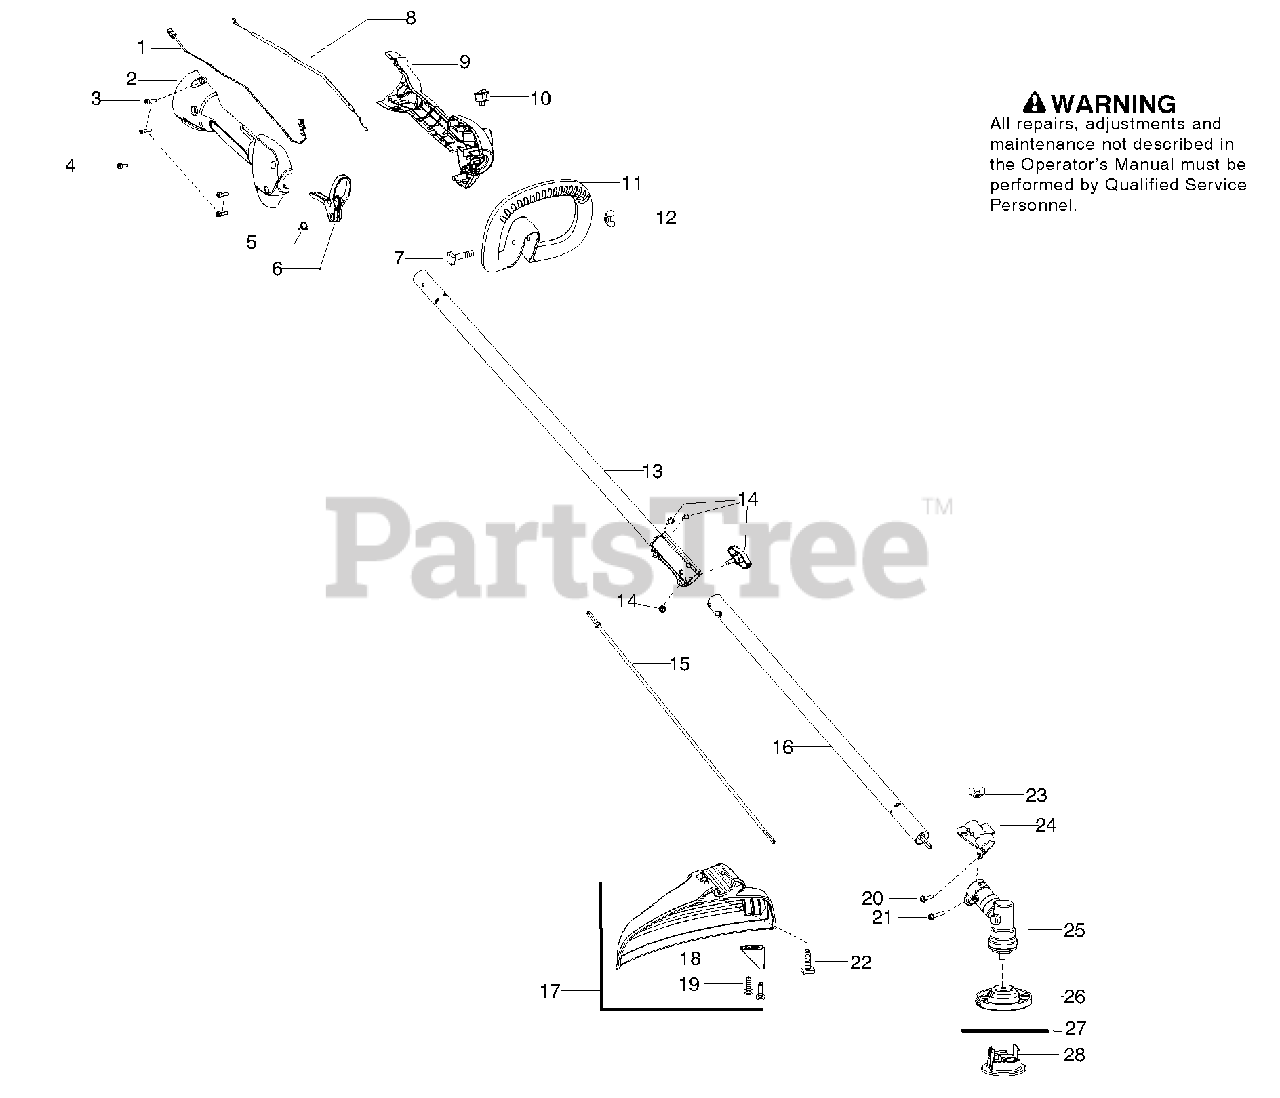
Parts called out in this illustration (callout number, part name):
1	Assy-Switch Wire
2	Housing-Throttle (RH)
3	Screw M4
4	Screw 10-14 x 1/2
5	Spring-Trigger
6	Kit - Trigger
7	Bolt - 1/4-20 x 2
8	Assy - Throttle Cable
9	Housing-Throttle (LH)
10	Kit-Switch
11	Assy - Handle Assist
12	Wingnut - 1/4-20
13	Kit-Driveshaft Upper
14	Kit - Knob / Screw
15	Flexshaft
16	Kit-Driveshaft Lower
17	Kit-Shield
18	Limiter-Line
19	Screw - 10-14 x 3/4
20	Screw - 8-16 x .593
21	Screw - 12-24 x .960
22	Bolt - 1/4-20 x 1-1/4
23	Wingnut - 1/4-20
24	Bracket - Shield
25	Assy - Gearbox 1"
26	Assy - Fixed Line Head
27	Accy - Line (12 pcs )
28	Cap - Fixed Line
